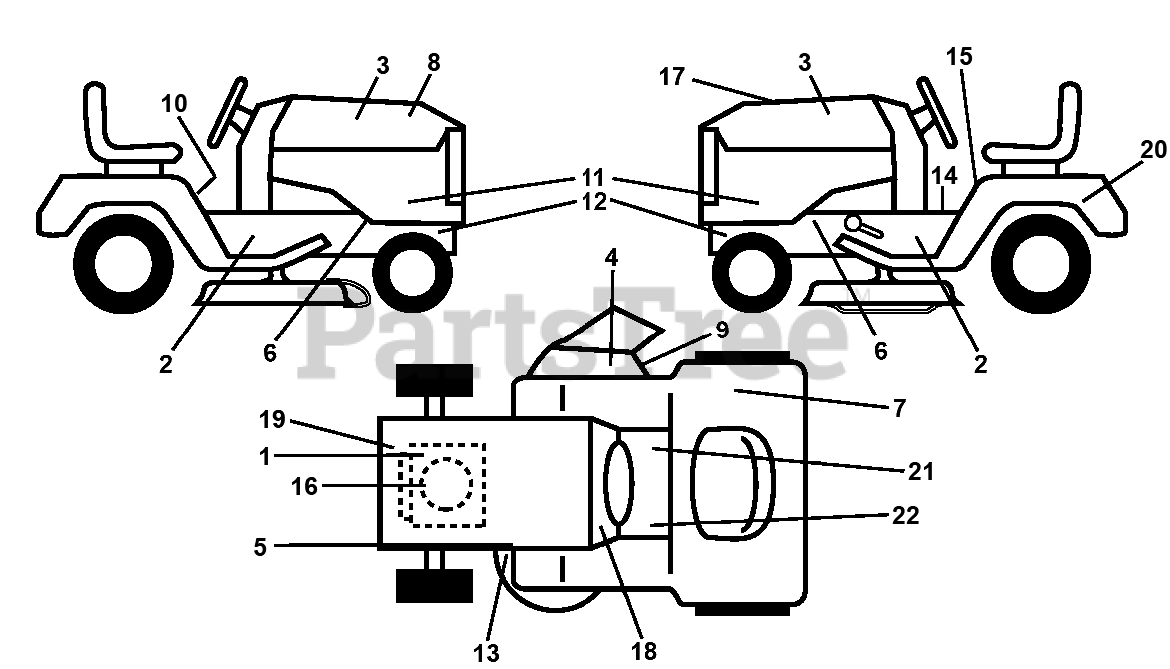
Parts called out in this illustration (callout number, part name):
1	DECAL.ENGINE.WARNING
2	DECAL.WARNING.SERVCE/FIRE
3	DECAL.WB.178MM.15.HUSQ.NEWBRAN
3	DECAL.BADGE.170MM.TEXTLOGO.
3	Decals
4	DECAL, DECK DEFLECTOR, WARNING
4	DECAL.DECK.DEFLECTOR.WARNING
5	DECAL.V-BELT.SCH.42/46"MEC/ELE
6	DECAL.CHASSIS.HOT.MUFFLER
6	DECAL.WARNING.HOT.MUFFLER.2021
7	Decals
8	Decals
9	DECAL.DFLCTR.WARNNG.CTFNGR.SYM
10	DECAL.TRACTOR.SADDLE
11	Decals
11	DECAL.SDPNL.HUSQLT.TS142.HUSQV
12	DECAL.WARNING.SERVCE/FIRE
13	DECAL.DECK.BELT.ROUTE.42"2021
13	DECAL.V-BELT.SCH.42/46"MEC/ELE
14	DECAL.READ.OWN.MAN.SYMBOL.LT
14	DECAL.TRACTOR.SADDLE
14	DECAL TRACTOR SADDLE DECAL DEC
15	DECAL.WARNING.2007.ENG/FR
16	DECAL.BS.ENDUR.18_5HP.382024
17	DECAL DECAL.RPL.BSM31.INTK.TLW
17	DECAL.RPL.BSM31.HUSQ.TLW
17	Decals
18	DECAL.SNOWFLAKE.MS498.HUSQ
19	DECAL.ENG.B&S.HS.500CC.382338
20	DECAL BTRY SYMBOLS
21	DECAL.PARKING.BRAKE.SADDLE.LT
22	DECAL.FNDR.SDLE.BRAKE.CLUTCH.6
